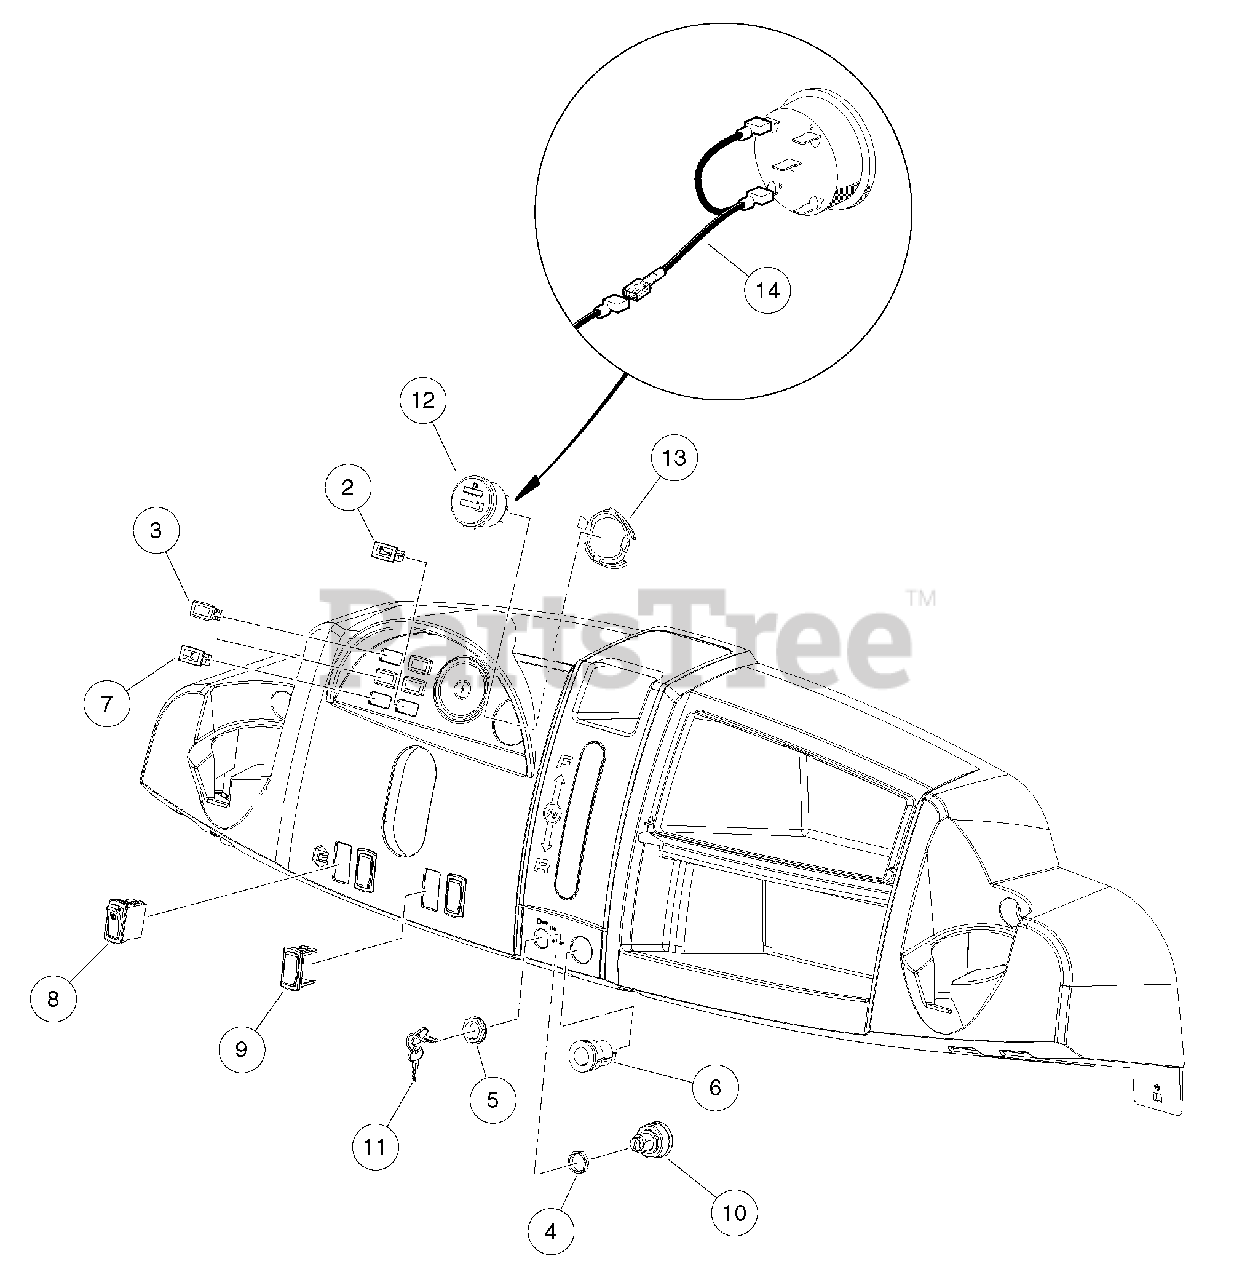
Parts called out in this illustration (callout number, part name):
1	Instl, Elec Sys, Restyle Diesl
2	Light, Oil
3	Plug, Hole
4	Spacer, Keyswitch
5	Nut, Key Switch
6	Receptacle, Accessory
7	Light, Indicator, Coolant Temp
8	Switch, Rocker, Light
9	Cover, Hole, Switch, Rocker
10	Keyswitch, 12v, Diesel
11	Keys (set of 2)
12	Gauge Fuel-hour Sep Gnd
13	Clip, Meter, Round
14	Asm Wire Meter F-h Jumper
